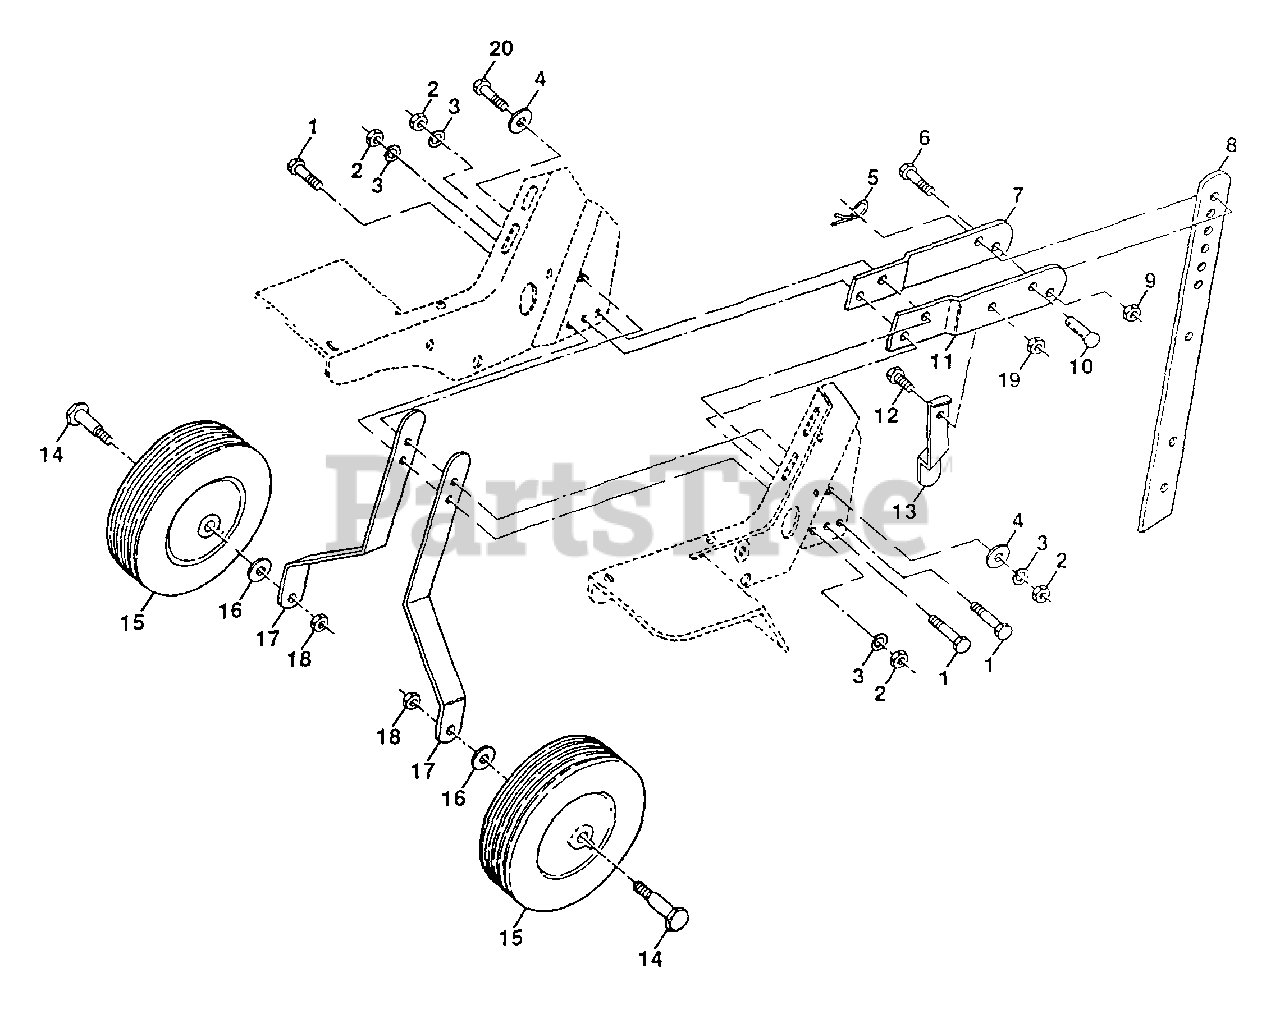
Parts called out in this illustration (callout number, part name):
1	Bolt, Hex 5/16-18 x 1-1/4
2	Nut, Hex 5/16-18
3	Washer, Lock 5/16
4	Washer 3/8 x 7/8 x 14 Ga.
5	Clip, Hairpin
6	Bolt, Fin, Hex 3/8-16 x 1-3/4
7	Support, Depth Stake, R.H.
8	Depth Stake
9	Locknut, w/Insert 3/8-16
10	Pin, Clevis
11	Support, Depth Stake, L.H.
12	Bolt, Hex 5/16-18 x 3/4
13	Spring, Depth Stake
14	Bolt, Shoulder
15	Wheel
16	Washer 13/32 x 13/16 x 11 Ga
17	Bracket, Wheel
18	Nut, Crownlock 3/8-16
19	Locknut, w/Insert 5/16-18
20	Bolt Hex 5/16-18 x 1-1/2
